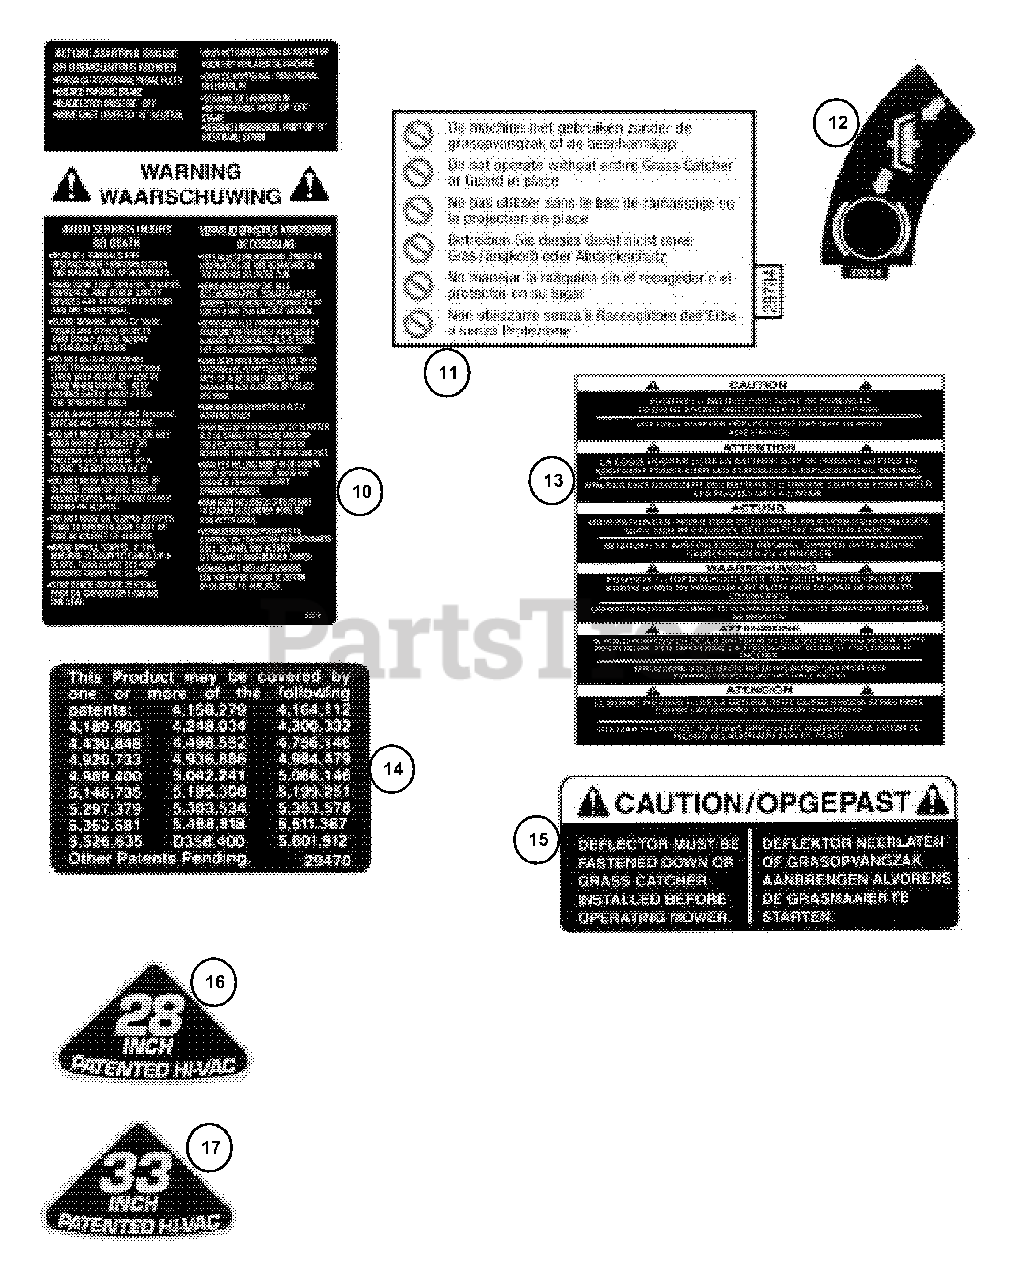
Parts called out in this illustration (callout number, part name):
10	DECAL, SAFETY Instruction (English & Dutch)
11	DECAL, DO NOT OPERATE!
12	DECAL, Clutch/Brake
13	DECAL, Battery CAUTION
14	DECAL, Patent Numbers
15	DECAL, Deflector CAUTION (English & Dutch)
16	DECAL, 28 Inch (Hi-Vac)
17	DECAL, 33 Inch (Hi-Vac)
